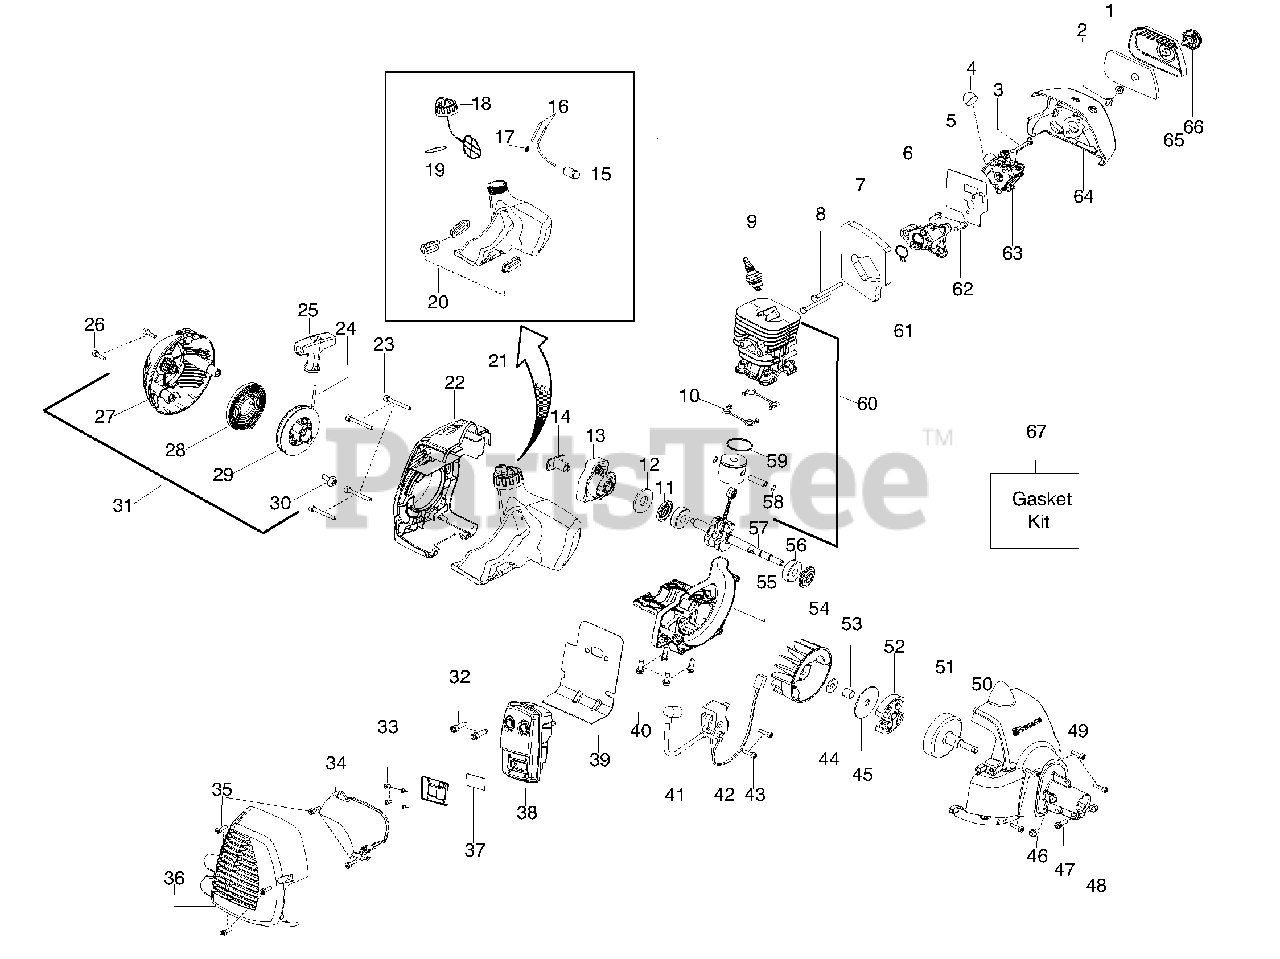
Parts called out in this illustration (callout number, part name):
2	Nut - Carb. Screw
3	Lever - Choke
4	Bulb - Purge
5	Kit-Carb. Gasket
6	Adaptor - Carb.
7	Foam - Gasket (kit)
9	Plug - Spark (RCJ-6Y)
10	Seal - Cylinder (kit)
11	Seal - Crankshaft (kit)
12	Washer
13	Assy - Starter Cup
14	Coupling - Starter
15	Assy - Fuel Filter
16	Kit - Fuel Line
17	Fitting - Fuel Line
18	Assy - Cap w/ret.
19	O-Ring - Fuel Cap (kit)
20	Isolator - Fuel Tank
21	Kit - Fuel Tank
22	Shroud - Rear
24	Kit - Rope
25	Handle - Starter
27	Starter Hsg. w/eyelet
28	Kit - Starter Spring
29	Kit - Starter Pulley
31	Assy-Starter Hsg.
32	Bolt - Muffler
33	Screw
34	Shield - Heat
36	Guard - Muffler
37	Kit - Spark
38	Kit - Muffler
39	Gasket-Paper Met.(kit)
41	Module
42	Assy - Leadwire
45	Washer - Clutch
50	Assy - Fan Housing
51	Assy - Clutch Drum
52	Kit - Clutch Assy.
55	Crankcase - cast
57	Crankshaft - Assy
58	Retainer - Piston Pin
59	Ring - Piston
60	Kit - Cyl./Piston
61	Seal - adaptor (kit)
63	Kit - Carb.
64	Airbox
65	Cover - Air Box
66	Assy - Knob
67	Kit - Gasket
